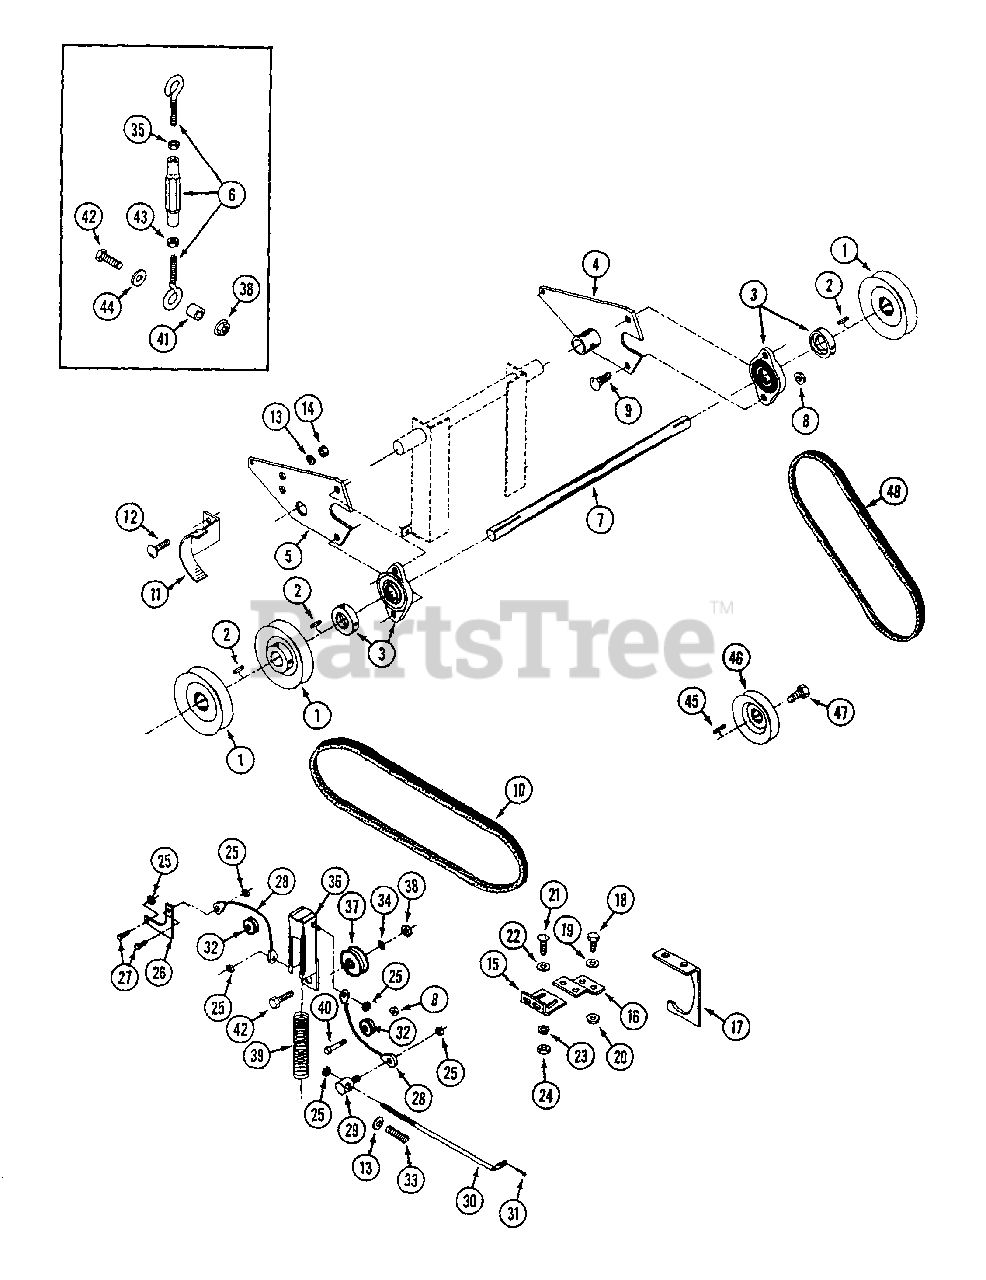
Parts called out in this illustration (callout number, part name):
1	PULLEY - 4" OD X 3/4" ID
2	KEY - 3/16" x 3/16" x 1"
3	BEARING - flanged
4	MOUNT - bearing L.H.
5	MOUNT - bearing R.H.
7	SHAFT - cross
8	NUT - 5/16" - 18 flange lock
9	BOLT - 5/16" - 18 x 1" carriage
10	BELT - drive 36"
11	RETAINER - cross shaft belt
12	BOLT - 1/4" - 20 x 3/4" carriage
13	LOCKWASHER - 1/4"
14	NUT - 1/4" - 20
15	BRACKET - engine belt retainer
16	BRACKET - engine belt
17	RETAINER - engine belt
18	BOLT - 1/4" - 20 x 3/4"
19	WASHER - 1/4"
20	NUT - 1/4" - 20 flange lock
21	BOLT - 5/16" - 20 x 1" carriage
22	WASHER - 3/8"
23	LOCKWASHER - 5/16"
24	NUT - 5/16" - 18
25	NUT - nylock 1/4" - 20
26	BRACKET - "L". brake linkage
27	BOLT - 1/4" - 20 x 1"
28	CABLE - clutch, brake
29	COLLAR - caliper rod
30	ROD - caliper, brake
30	ROD - clutch
31	PIN - cotter - 3/32" x 1"
32	PULLEY - 1-1/2" OD
33	SPRING - caliper rod
34	LOCKWASHER - 3/8"
35	NUT - 3/8" - 16
36	TUBE - drive idler
37	PULLEY - idler 2-1/4" O.D.
38	NUT - 3/8" - 16 flange lock
39	SPRING - belt tightener
40	BOLT - 5/16" - 18 x 2-1/4"
42	BOLT - 3/8" - 16 x 1-1/2"
43	NUT - 3/8" - 16 L.H. threads
45	KEY - 5 x 5 x 25 mm
46	PULLEY - pump
47	BOLT - M6 - 1.0 x 12 flange
48	BELT - pump 26"
